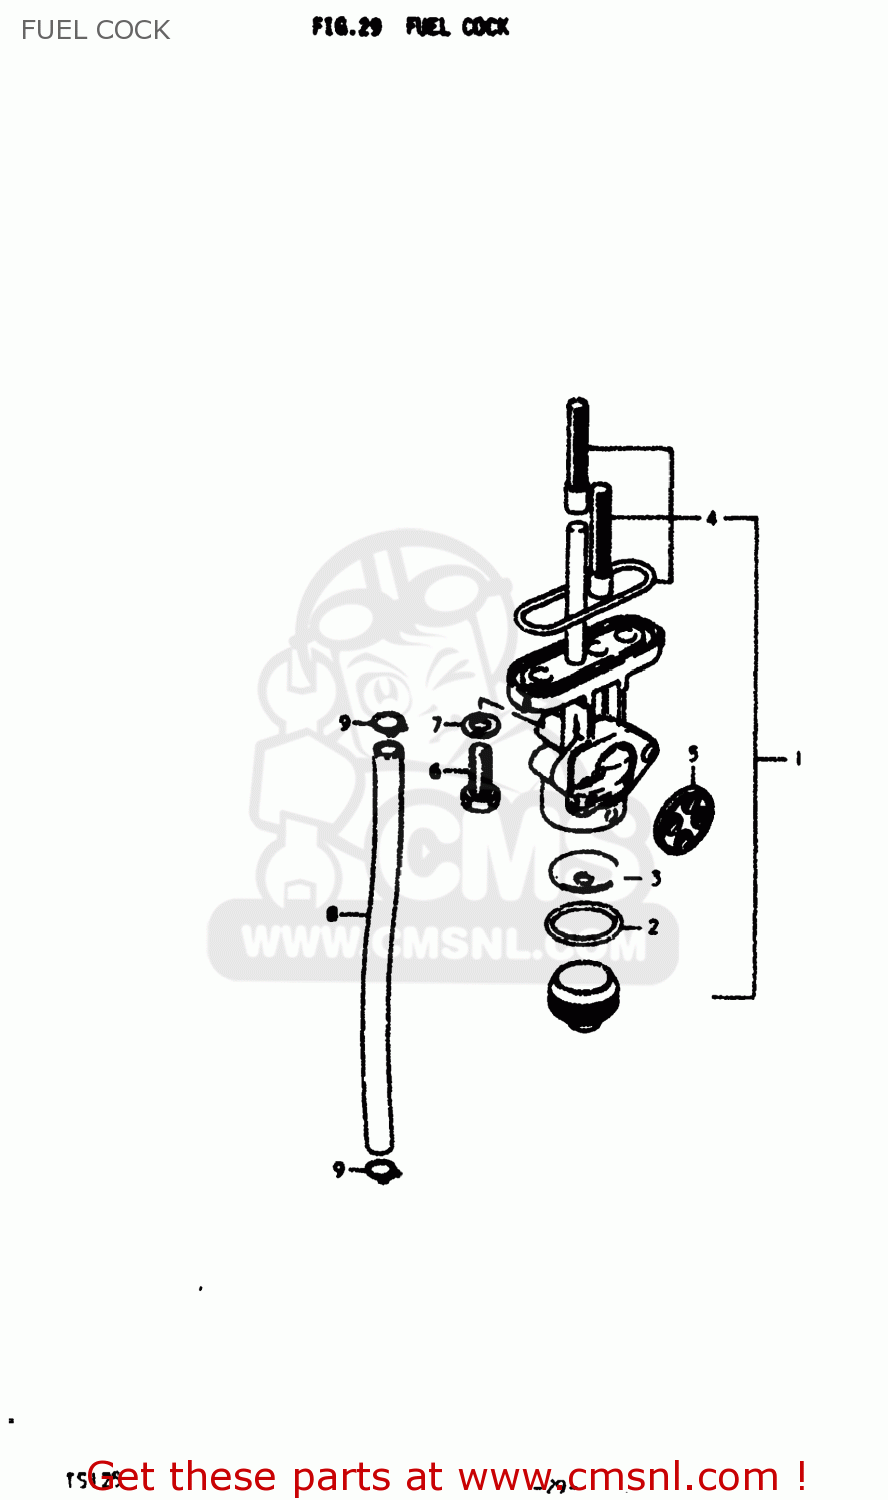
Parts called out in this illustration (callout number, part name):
1	COCK ASSEMBLY,FUEL
2	GASKET,FILTER (NAS)
3	NET,STRAINER
4	FILTER SET,FUEL COCK
5	GASKET,LEVER (NAS)
6	BOLT L:16
7	GASKET
8	HOSE
9	CLIP
